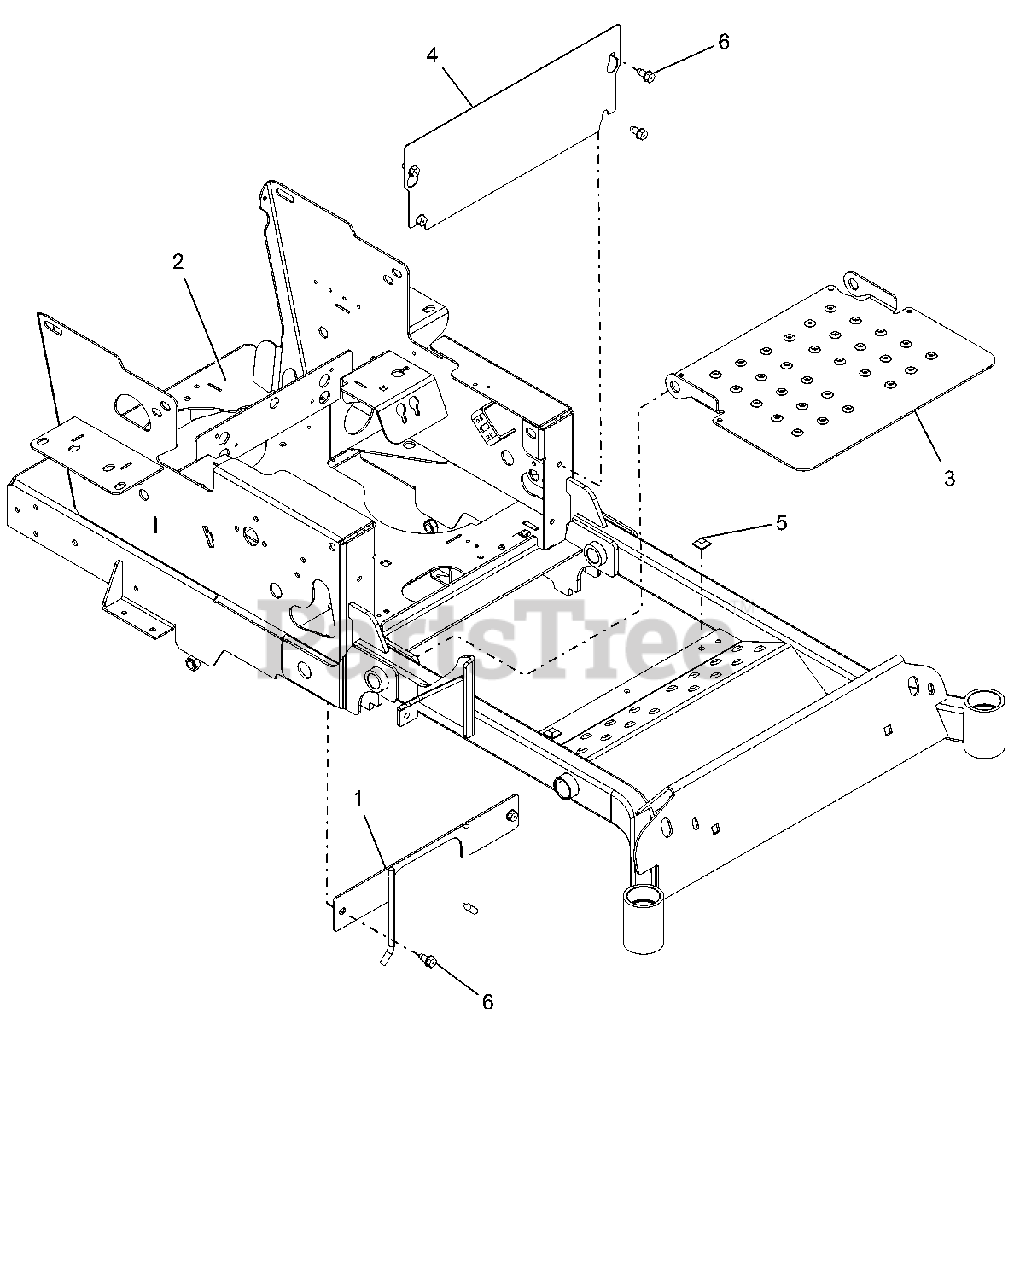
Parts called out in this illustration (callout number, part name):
1	PTO BELT FINGER WLDMT - BLK
2	HD 44-48 FRAME W/SAFETY DECALS
3	INSPECT PNL W/SAFETY DECAL-ORG
4	PLATE, KICK
6	@SCR-TAP .38-16X.75 HWH TR YWZ
